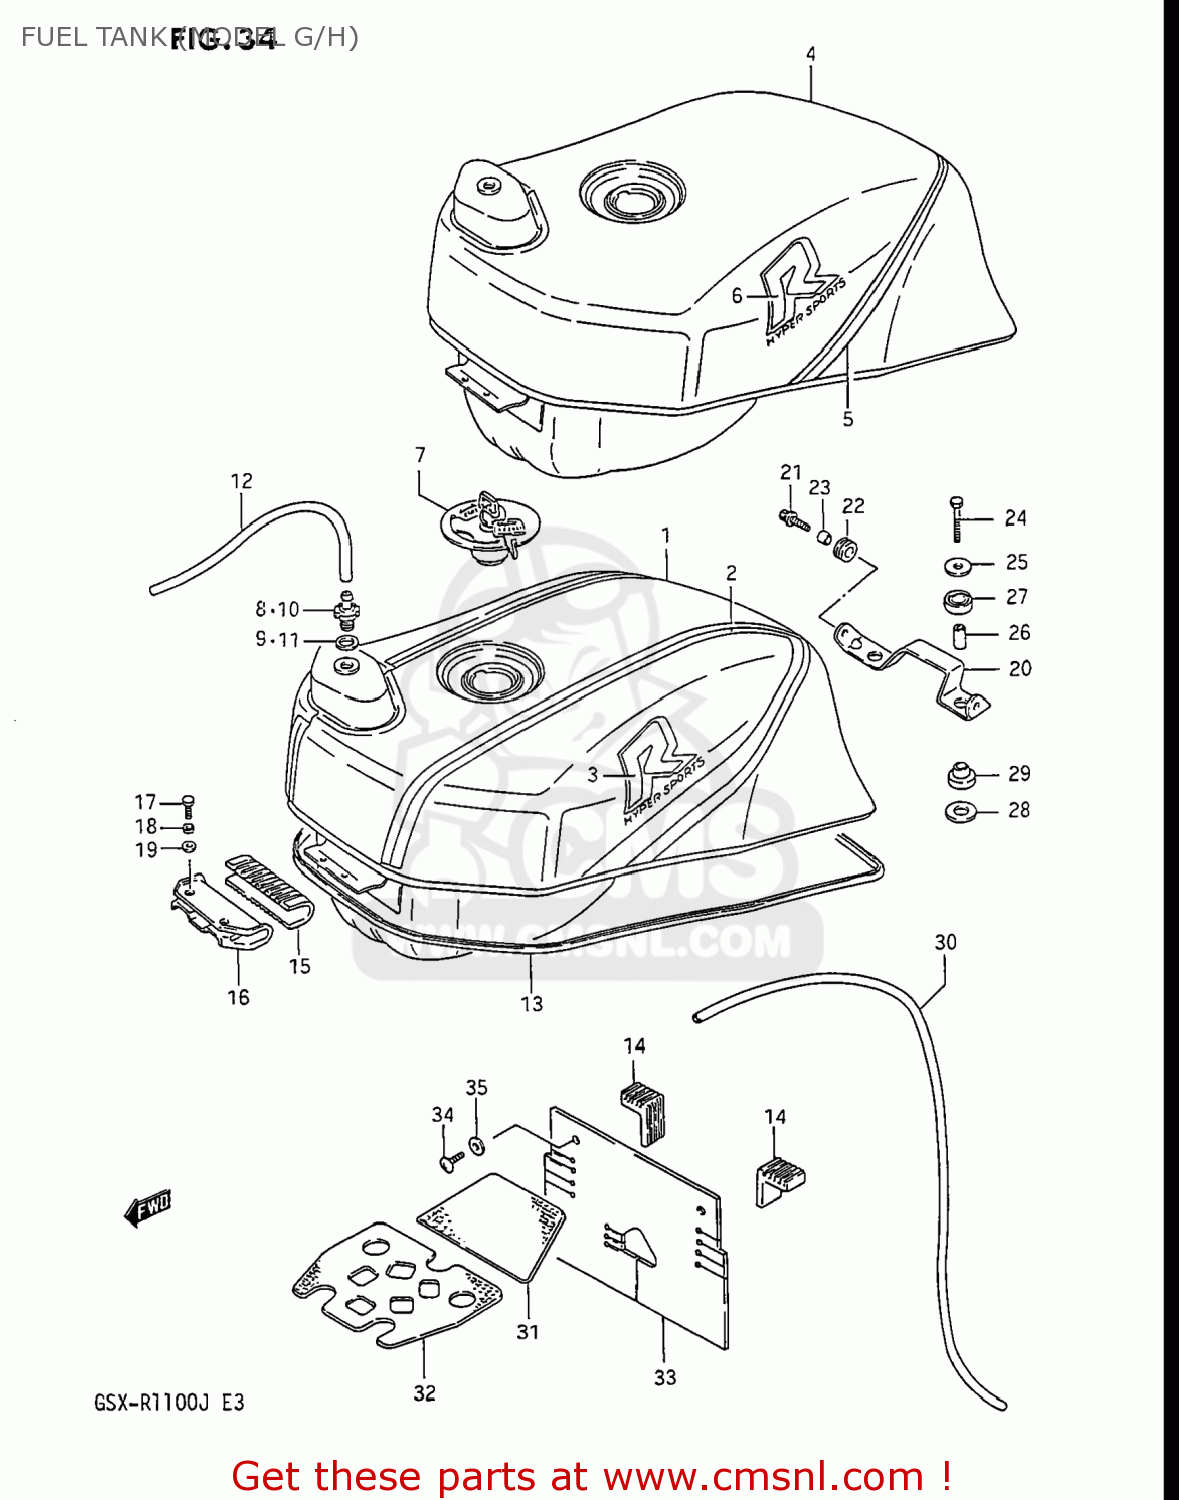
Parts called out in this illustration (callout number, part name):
1	TANK ASSEMBLY,FUEL
2	TAPE SET,FUEL TANK
3	EMBLEM
4	TANK ASSEMBLY,FUEL
5	TAPE SET,FUEL TANK
6	EMBLEM,FUEL TANK
7	CAP SET,FUEL TANK
8	PLUG,FUEL TANK BREATHER
9	GASKET(12.5X20X2.5) (NAS)
10	(CA) VALVE,FUEL TANK BREATHER
11	GASKET 27X40X2.5 (NAS)
12	HOSE,FUEL
13	MOLDING,FUEL TANK
14	CUSHION,FUEL TANK SIDE
15	CUSHION,FUEL TANK FR
16	BRACKET,FUEL TANK FR
17	BOLT
18	WASHER,LOCK
19	WASHER
20	BRACKET,SEAT SUPPORT,FRONT
21	BOLT
22	CUSHION
23	SPACER(6.1X9X7.5)
24	BOLT ,6X35
25	WASHER (6.5X24X1.6)
26	SPACER
27	CUSHION
28	WASHER (12.5X24X1.6)
29	CUSHION
30	HOSE,FUEL
31	SHIELD,FUEL TANK HEAT
32	SHIELD,FUEL TANK HEAT
33	SHIELD,HEAT NO.1
34	SCREW
35	WASHER
